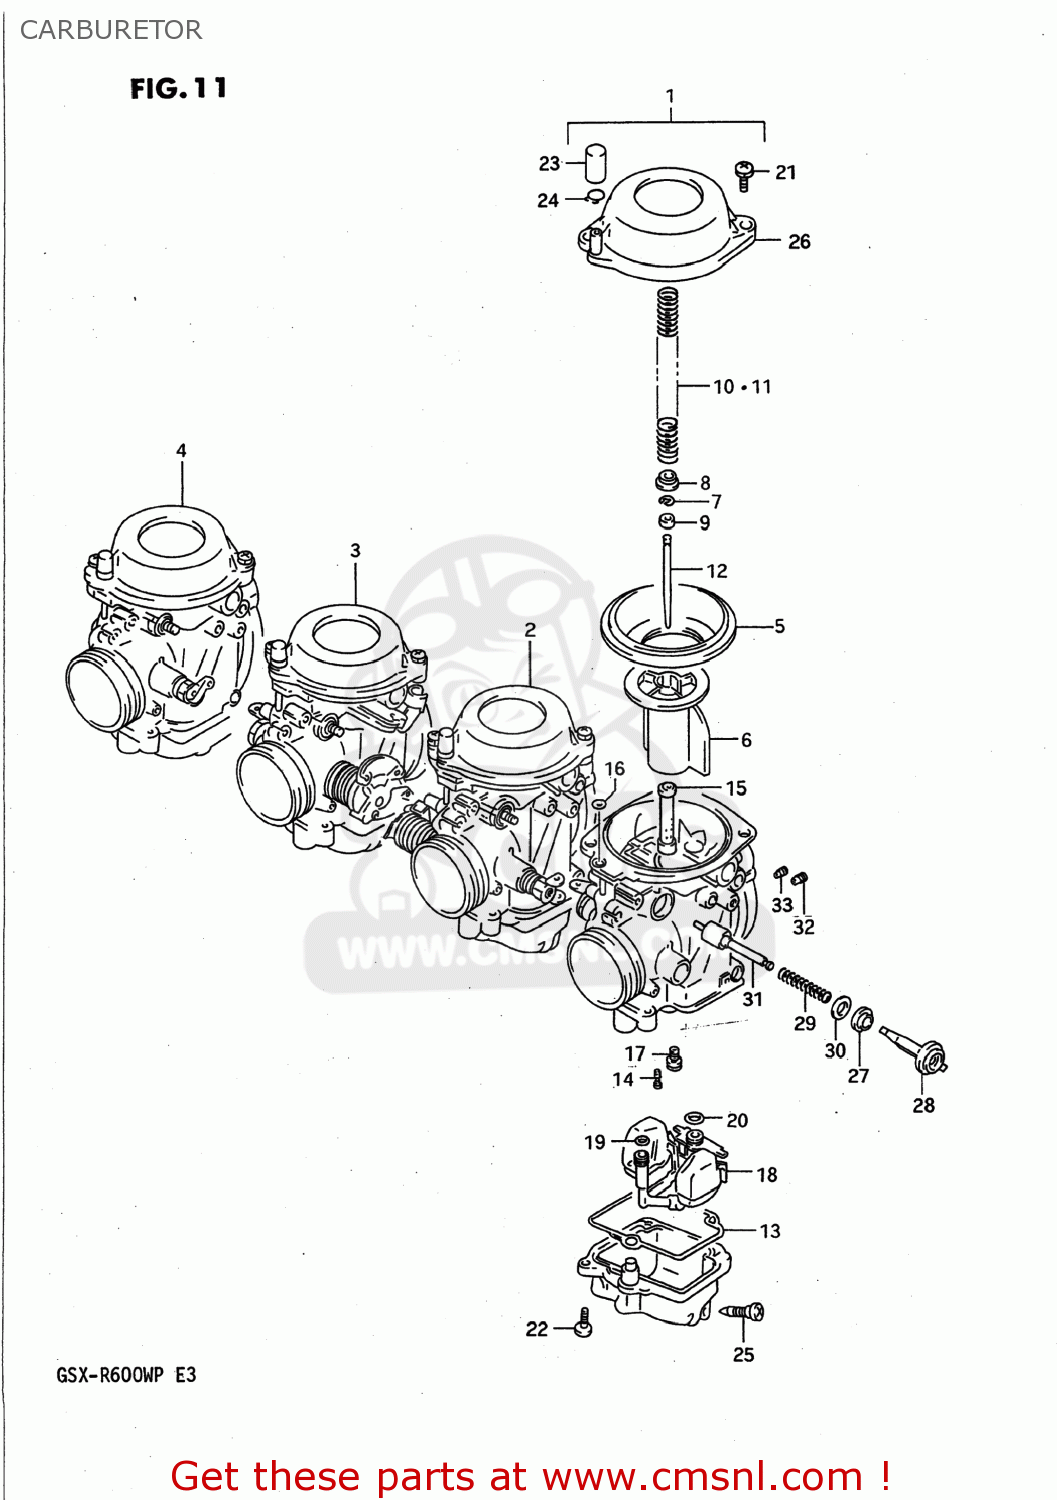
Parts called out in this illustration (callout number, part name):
1	CARBURETOR ASSEMBLY,LEFT
2	CARBURETOR ASSEMBLY,MIDDLE,LEFT
3	CARBURETOR ASSEMBLY,MIDDLE,RIGHT
4	CARBURETOR ASSEMBLY,REAR
5	DIAPHRAGM
6	VALVE,PISTON
7	CLIP,NEEDLE
8	RING
9	RING
10	SPRING
11	SPRING
12	NEEDLE,JET
13	GASKET,FLOAT CHAMBER (NAS)
14	JET,PILOT(32.5)
15	JET,NEEDLE(X-9)
16	O RING
17	JET,MAIN(105)
18	FLOAT/NEEDLE VALVE ASSY
19	O RING
20	O-RING,NEEDLE VALVE
21	SCREW
22	SCREW
23	CAP
24	CLIP
25	SCREW,DRAIN
26	COVER,DIAPHRAGM
27	CAP,STARTER
28	HOLDER,GUIDE
29	SPRING
30	WASHER
31	PLUNGER ASSY
32	JET,AIR(0.6)
33	JET,AIR
